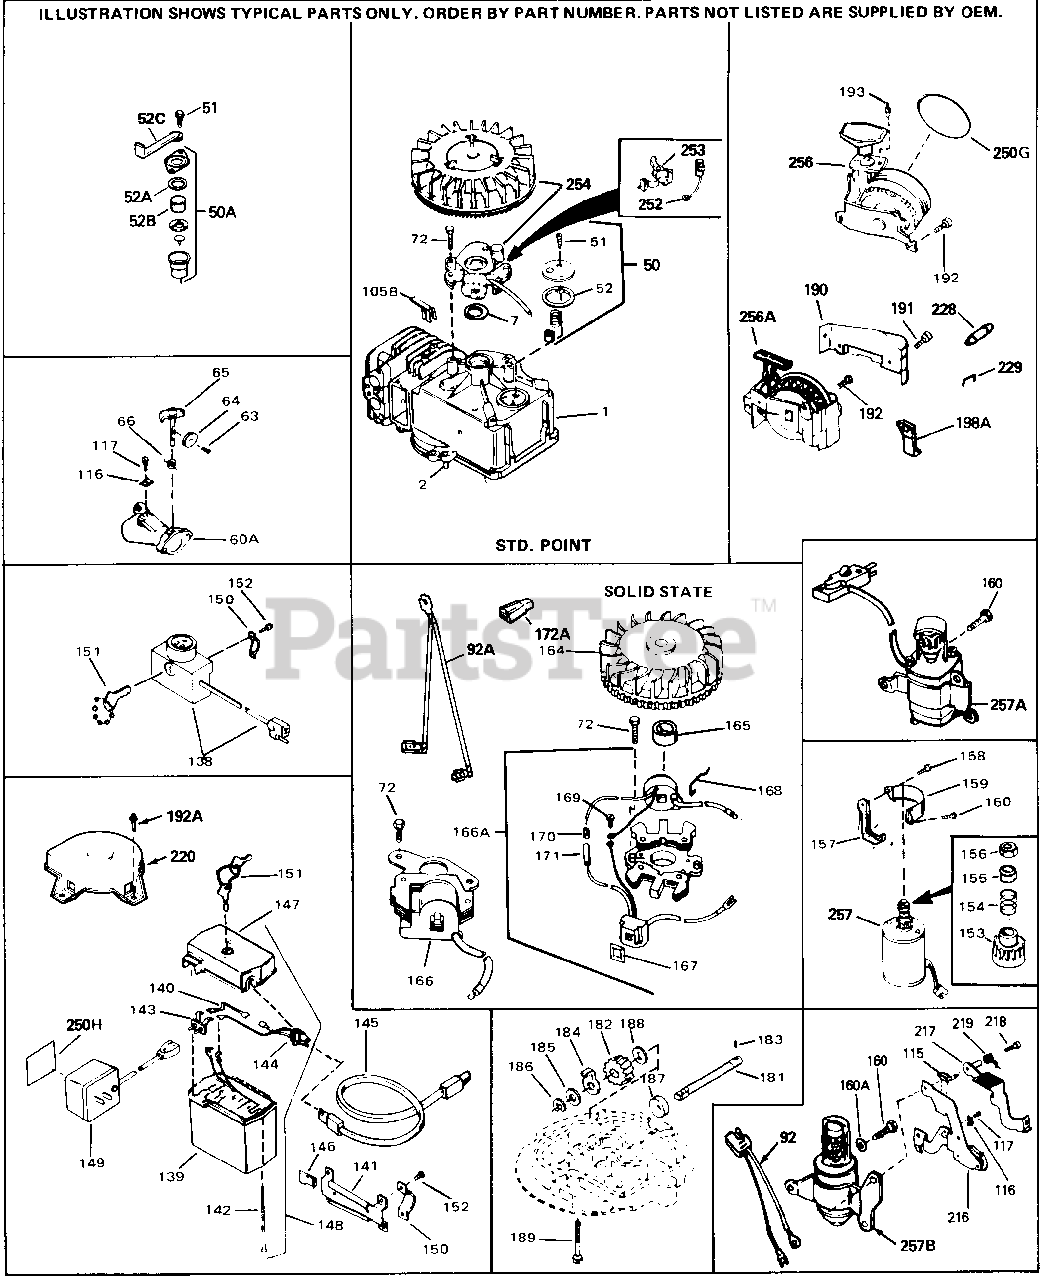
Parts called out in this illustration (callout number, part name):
1	"Cylinder Assy. (2-5/8" Bore)
2	Pin, Dowel
7	Gasket, Stator
50	Breather Assy.
51	Screw, Hex washer hd. self-tap Sems, 10-24 x
52	Gasket, Breather
63	Screw, Pan washer hd., 4-40 x 3/16
64	Shutter, Throttle
65	Shaft, Throttle
66	Spring, Throttle return
72	Screw, Hex hd. Sems, 1/4-20 x 5/8
92A	Wire, Ground (Two female & one double male
115	Terminal Assy.
192	Screw, Hex washer hd. taptite, 1/4-20 x 5/8
192A	Rivet, Pop (3/16" Dia.)
252	Condenser
253	Contact Assy., Breaker
256A	Starter, Side mount rewind
